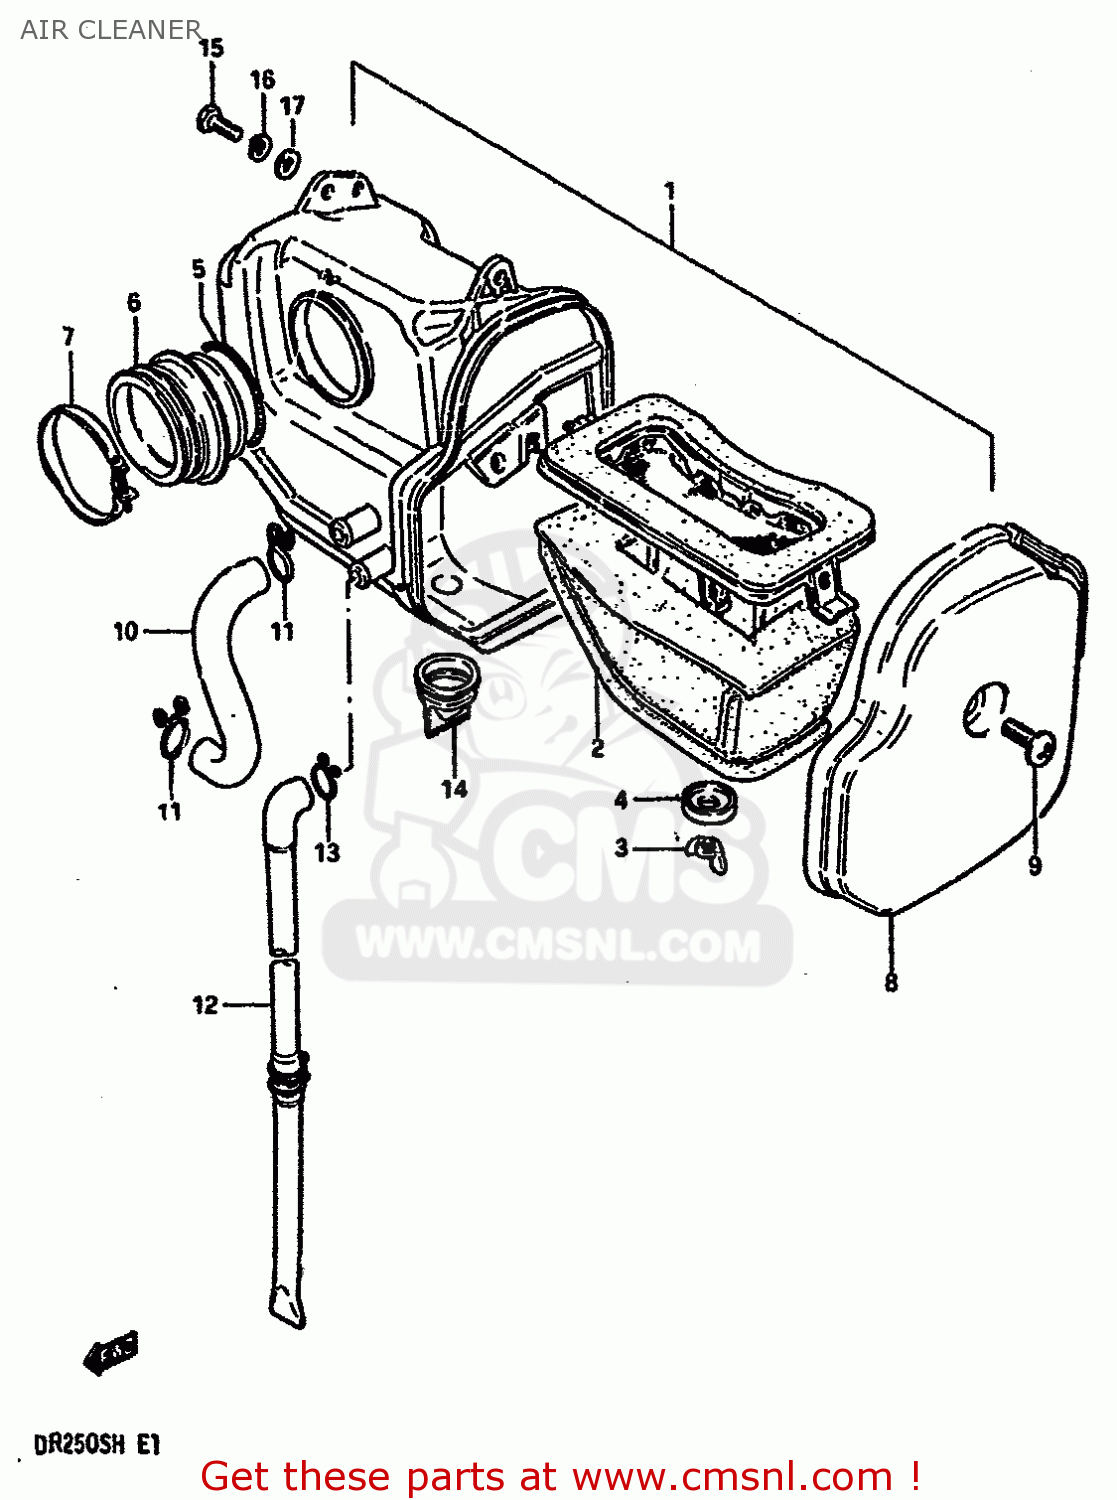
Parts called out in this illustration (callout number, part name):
1	CLEANER ASSEMBLY,AIR
2	ELEMENT,AIR CLEANER
3	NUT
4	WASHER
5	CLAMP,CLEANER SIDE
6	TUBE,AIR CLEANER OUTLET
7	CLAMP
8	CAP
9	SCREW
10	TUBE,BREATHER
11	CLAMP
12	DRAIN TUBE
13	CLIP
14	HOSE,AIR CLEANER DRAIN
15	BOLT
16	WASHER,LOCK
17	WASHER
